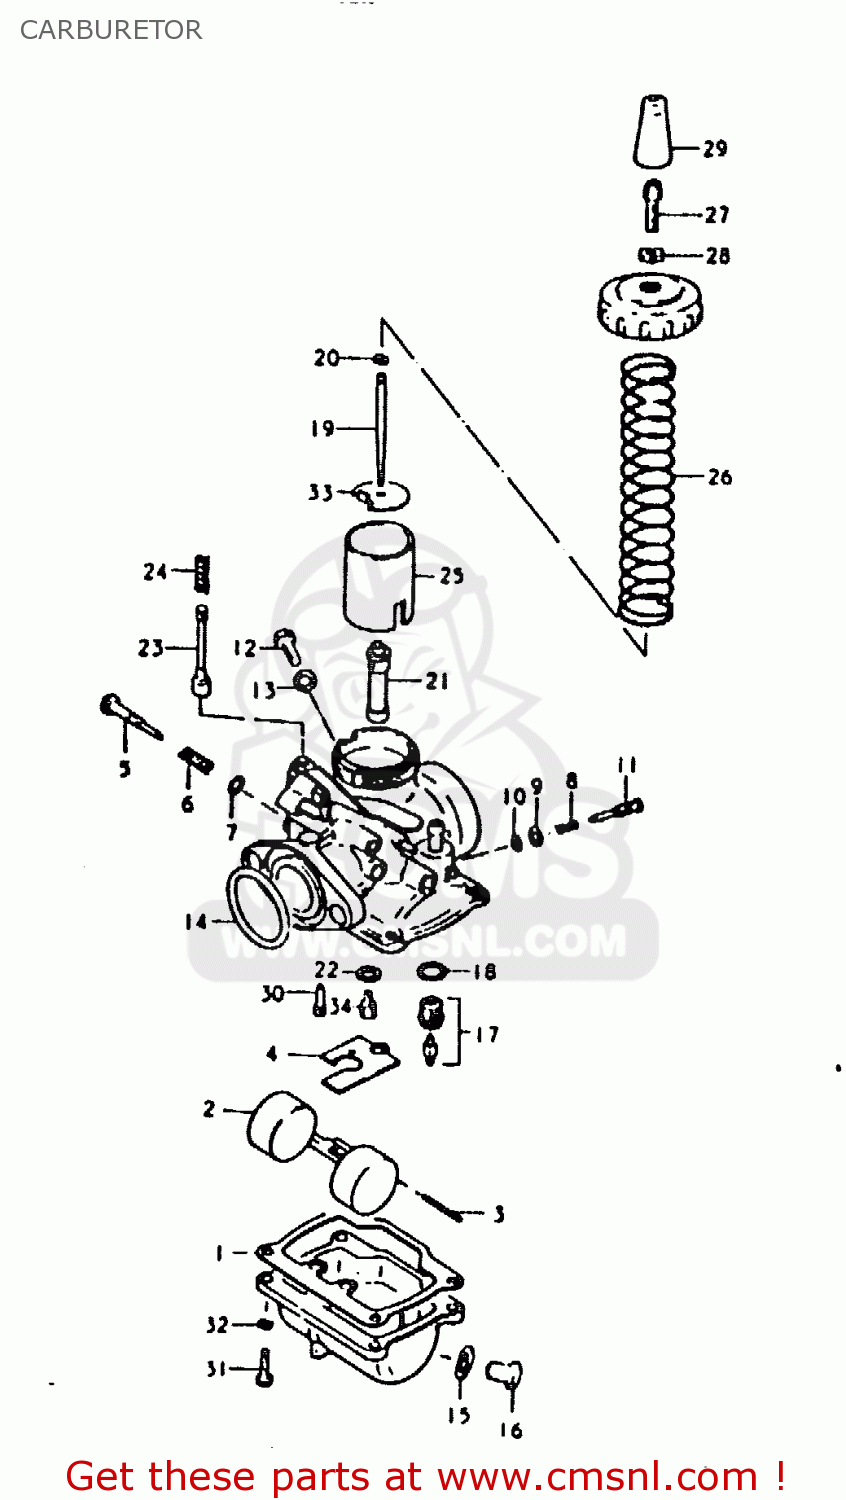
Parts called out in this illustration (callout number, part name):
1	GASKET,FLOAT CHAMBER (NAS)
2	FLOAT
3	PIN,FLOAT
4	PLATE
5	SCREW,THROTTLE STOP
6	SPRING,PILOT
7	O-RING
8	SPRING
9	WASHER,PILOT AIR SCREW
10	O RING
11	SCREW,PILOT AIR
12	PLUG
13	GASKET,THRO VALVE INSPECTION (NAS)
14	O RING
15	GASKET,DRAIN,PLUG (NAS)
16	PLUG
17	VALVE ASSEMBLY,NEEDLE
18	GASKET,VALVE SEAT (NAS)
19	NEEDLE,JET
20	CLIP
21	JET,NEEDLE
22	WASHER
23	VALVE,STARTER
24	SPRING
25	VALVE,THROTTLE
26	SPRING, THROTTLE VALVE
27	ADJUSTER,CABLE
28	NUT
29	CAP
30	JET
31	SCREW
32	LOCK WASHER
33	SEAT,THROTTLE VALVE SPRING
34	JET,MAIN 85
